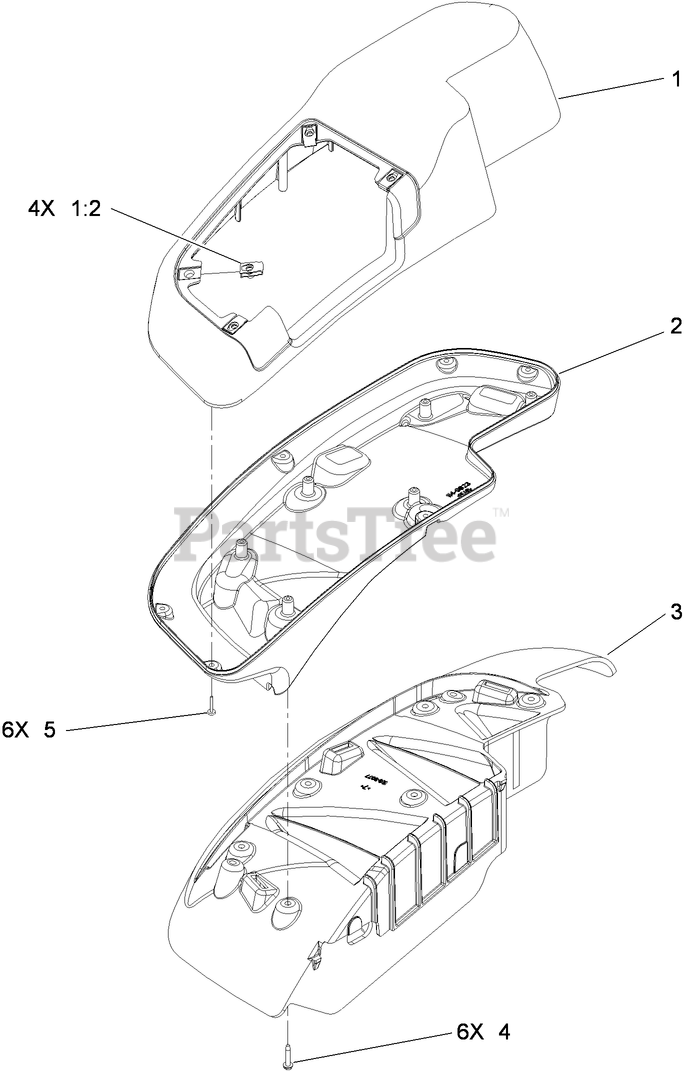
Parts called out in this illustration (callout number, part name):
1	RH CONSOLE TOP ASM
2	CONSOLE-NARROW, RH
3	FENDER-NARROW, RH
4	SCREW-THREAD FORMING
5	SCREW-PPH
